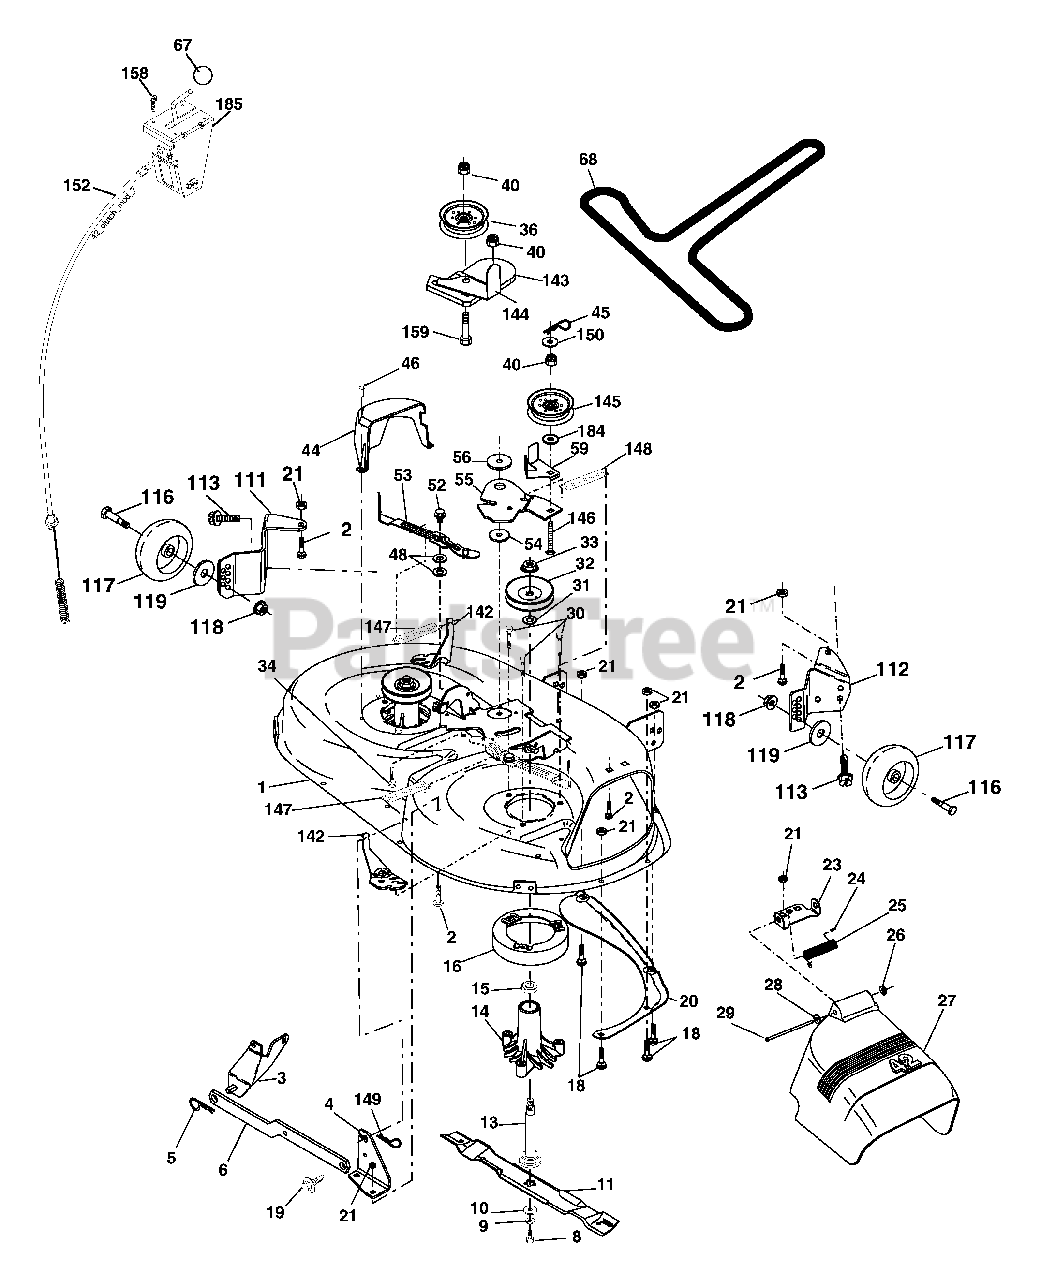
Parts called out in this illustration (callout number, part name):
1	Mower Deck Assembly, 42"
2	Bolt
3	Bracket Asm Fr. Sway Bar 3/42
4	Bracket Asm Deck 42" Sway Bar
5	Retainer Spring
6	Bar Sway Deck
8	Bolt 3/8-24 x 1.25 Gr. 8 patched
9	Washer, Lock
10	Washer, Hardened
11	Blade, Mulching 42" Std
11	Blade Mulching 42" Premium
13	Shaft Assembly, Mandrel, Vented
14	Housing, Mandrel, Vented
15	Bearing, Ball, Mandrel
16	Stripper, Mandrel Deck
18	Bolt, Carriage 5/16-18 x 5/8
19	Bolt, Shoulder
20	Baffle, Vortex
21	Nut
23	Bracket, Deflector Mower 42"
24	Cap, Sleeve 80 x 112 Blk Mower
25	Spring, Torsion, Deflector 2 52
26	Nut, Push Phos & Oil
27	Shield, Deflector 42" Blk
28	Washer
29	Rod, Hinge 42" 6 75 W/G
30	Screw Thdrol
31	Washer, Spacer Mower Vented
32	Pulley, Mandrel
33	Nut, Toplock
34	Bolt Carr SH 3/8-16 x 1-1/2 Gr.5
36	Pulley, Idler, Flat
40	Nut Lock 3/8-16
44	Guard, Mandrel, LH
45	Retainer
46	Screw, Thdrol 1/4-20 x 5/8 T
48	Washer, Hardened
52	Bolt, Shoulder 5/16-18 unc
53	Arm Assembly, Pad, Brake
54	Washer, Hardened
55	Arm, Idler
56	Spacer, Retainer
59	Guard TUV Idler
67	Knob Round
68	V-Belt, 42" Mower
111	Bracket Wheel Gauge LH
112	Bracket Wheel Gauge RH
113	Screw 5/16-18 x 3/4
116	Bolt, Shoulder
117	Wheel, Gauge
118	Nut Centerlock 3/8-16
119	Washer 3/8 x 7/8 x 14 Ga.
142	Arm Spring Brake Mower
143	Bracket Arm Idler 42"
144	Keeper Belt 42" Clutch Cable
145	Pulley Idler Flat
146	Bolt Carriage Idler
147	Spring Extension
148	Spring Return Idler
149	Retainer Spring Yellow
150	Washer 9/32 x 3/4 x 10 Ga.
152	Clutch Cable 42"
158	Screw Hex Thd Cut 1/4-20 x 1/2
159	Bolt Rdhd Sqn 3/8-16 unc x 1-3/4
184	Washer 13/32 x 7/8 x 10 Ga.
185	Head Asm Cable Clutch
